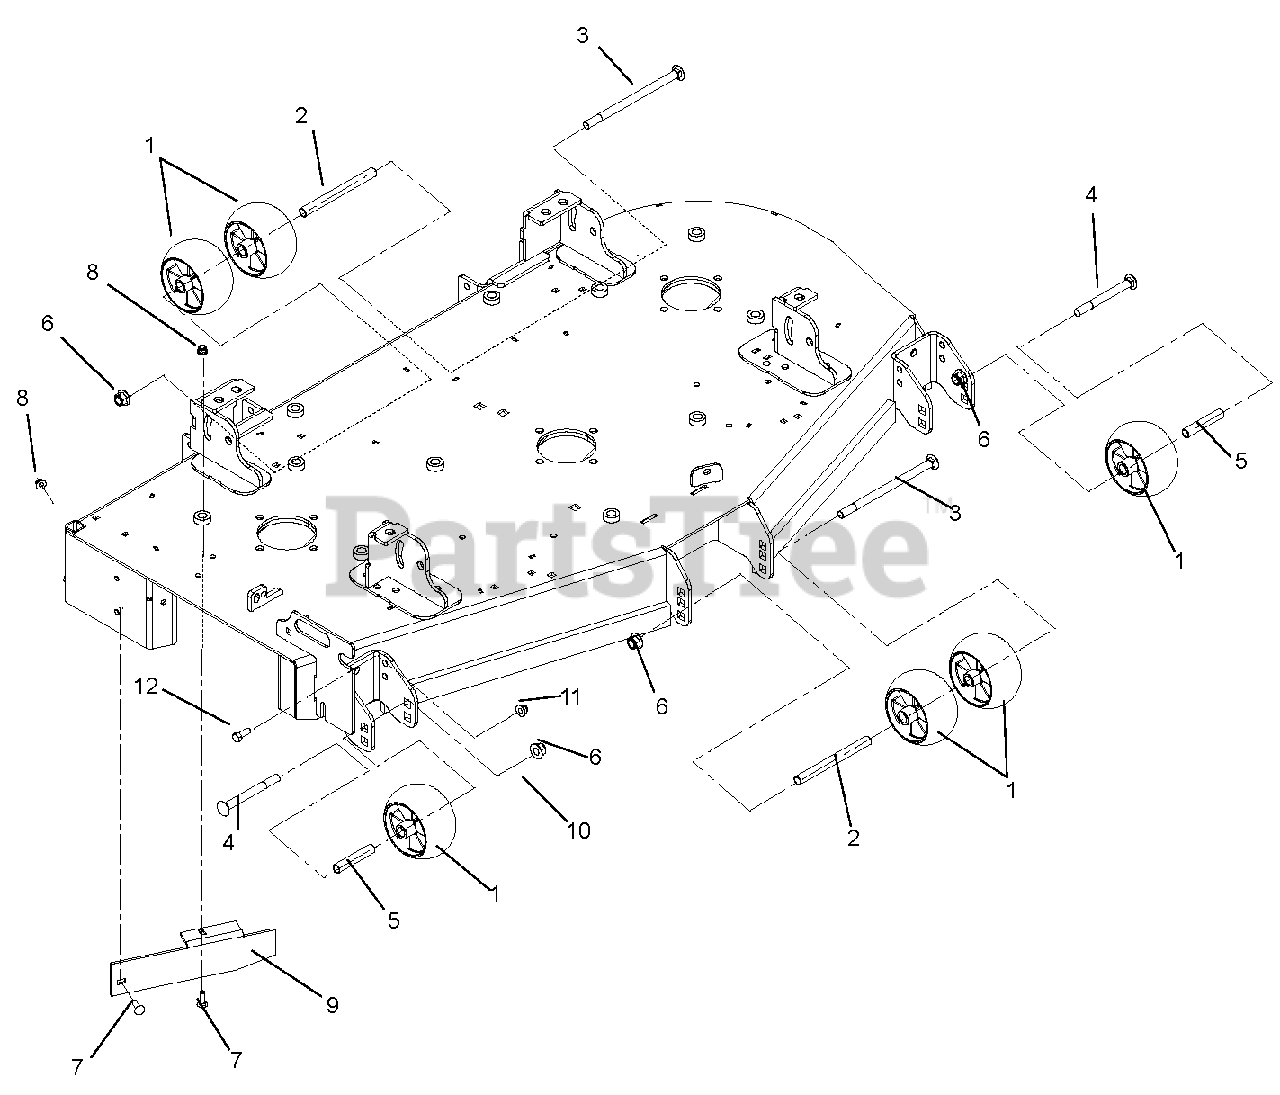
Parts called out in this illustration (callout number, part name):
1	Anti-Scalp Wheel, 5 x 3 Center
2	Spacer, .510 x .625 x 6.70
3	Bolt, Round Head Square Neck .50-13 x 8.50
4	Bolt, Round Head Square Neck .50-13 x 5.00
5	Spacer, .510 x .625 x 3.35
6	Nut, Locking Nyloc Flange .50-13
7	Bolt, Round Head Square Neck .31-18 x 1.00 Grade 5
8	Nut, Locking Nyloc Flange .31-18
9	Discharge Baffle 60" (992201, 203, 204, 198)
10	Bracket, Chute Storage
11	Nut, Locking Nyloc Flange .38-16
12	Bolt, Hex .38-16 x 1.00 Grade 5
